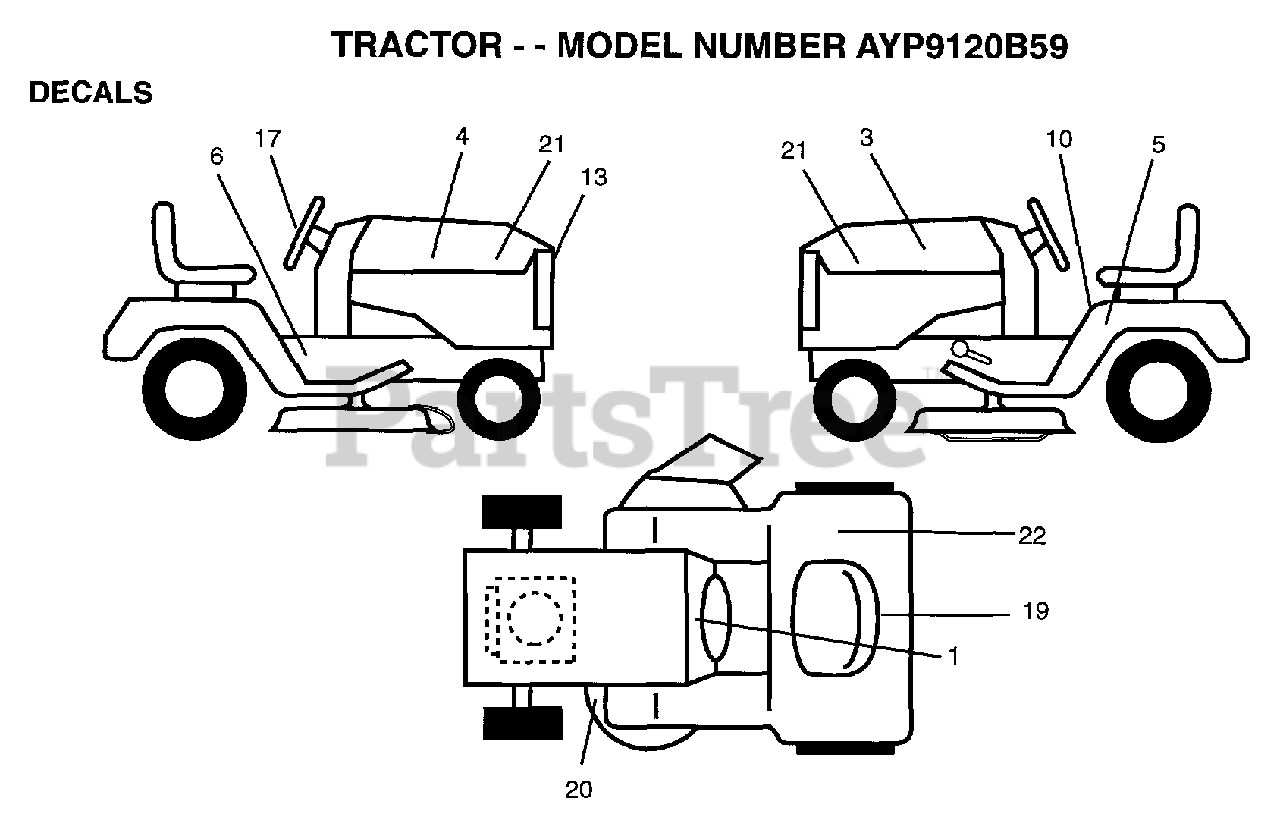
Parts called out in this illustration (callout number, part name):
1	DECAL.INST.OPER
3	DECAL STRIPE HOOD
4	DECAL STRIPE HOOD
5	DECAL
6	DECAL CHASSIS
10	DECAL
13	DECAL.GRILLE
19	DECAL
21	DECAL.INST.HD.WIZ
22	DECAL.BATRY.3-3908
